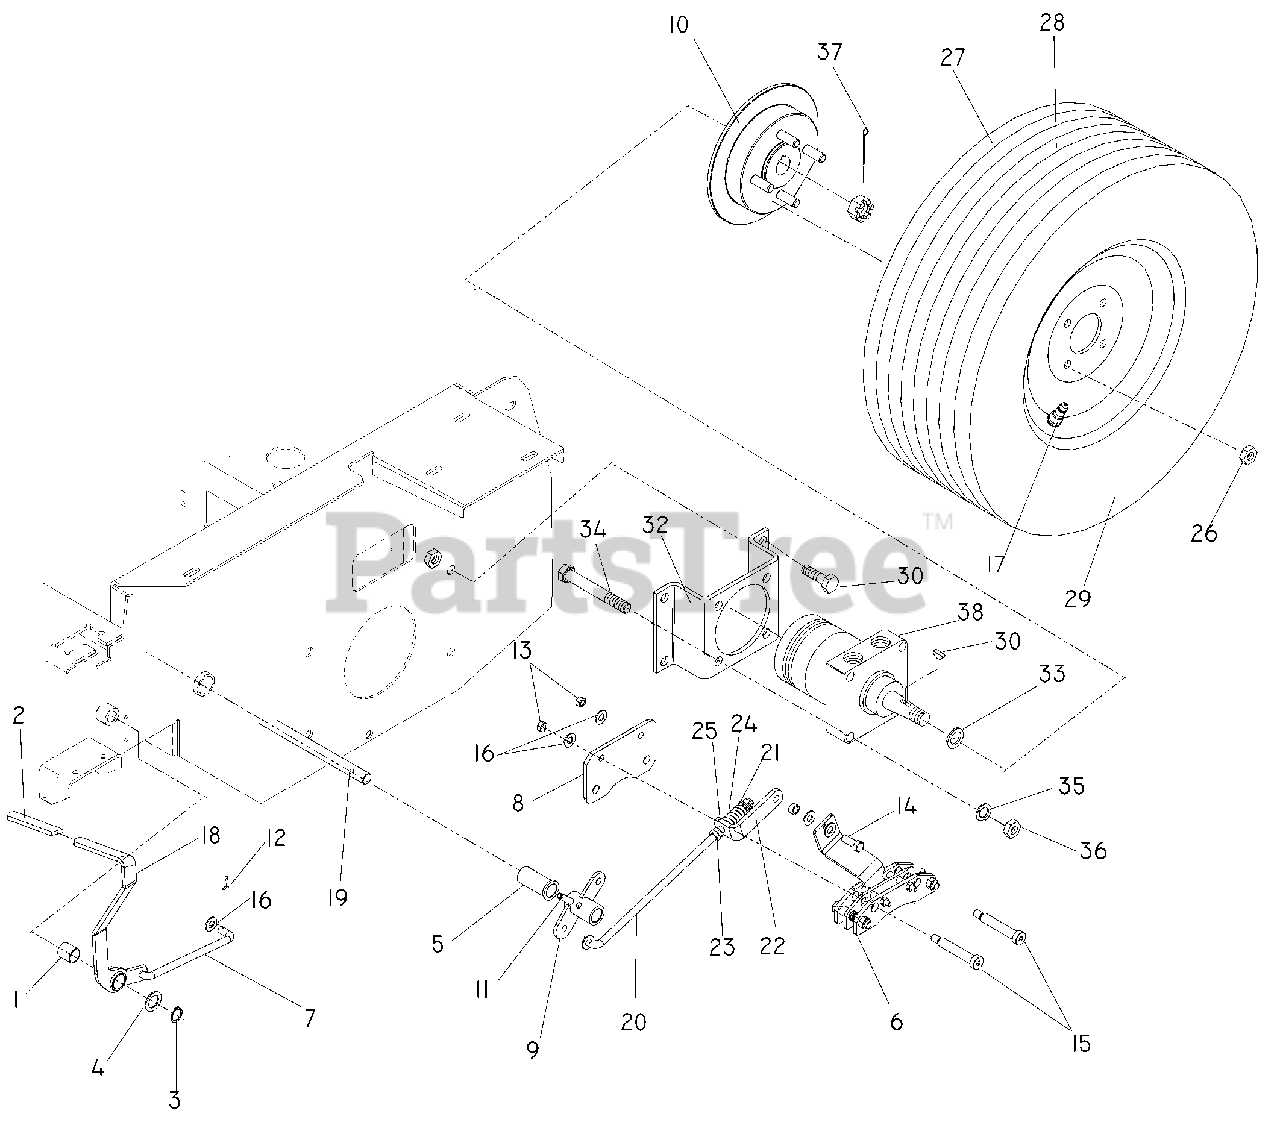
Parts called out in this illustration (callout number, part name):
3	RING, RETAINING, 7/8
4	BUSHING, MACHINE
5	BUSHING, POLYMER, ¾
6	CALIPER
7	LINKAGE, BRAKE
8	PLATE, BRAKE
9	BELLCRANK, BRAKE
11	PIN, ROLL, 5/16" DIA.
12	PIN, COTTER, 3/32 x ¾
13	NUT 3/8 -16, JAM, NYLOC
14	HCS, 3/8 -16 x 1
15	SB, 3/8 -16 x 2½, SKT HD
16	WASHER, 3/8 SAE FLT
17	VALVE STEM
18	BRAKE LEVER
19	SHAFT, CROSS
20	LINKAGE, REAR BRAKE
21	NUT 3/8 -24, CTR LK
22	BRACKET, L
23	NUT 3/8 -24, JAM
24	WASHER, 3/8, SAE
26	NUT LUG, ½F
27	TIRE, COMPLETE, 61" & 72"
28	TIRE, 24 x 12.0-12
30	KEY, WOODRUFF
31	NUT ½ -13, NYLOC
32	STANDOFF, WHEEL MOTOR
33	BUSHING, MACHINE, 1"
34	HCS, ½ -13 x 2¾
35	LOCKWASHER, ½
36	NUT ½ -13
37	PIN, COTTER
38	WHEEL MOTOR, TL15
